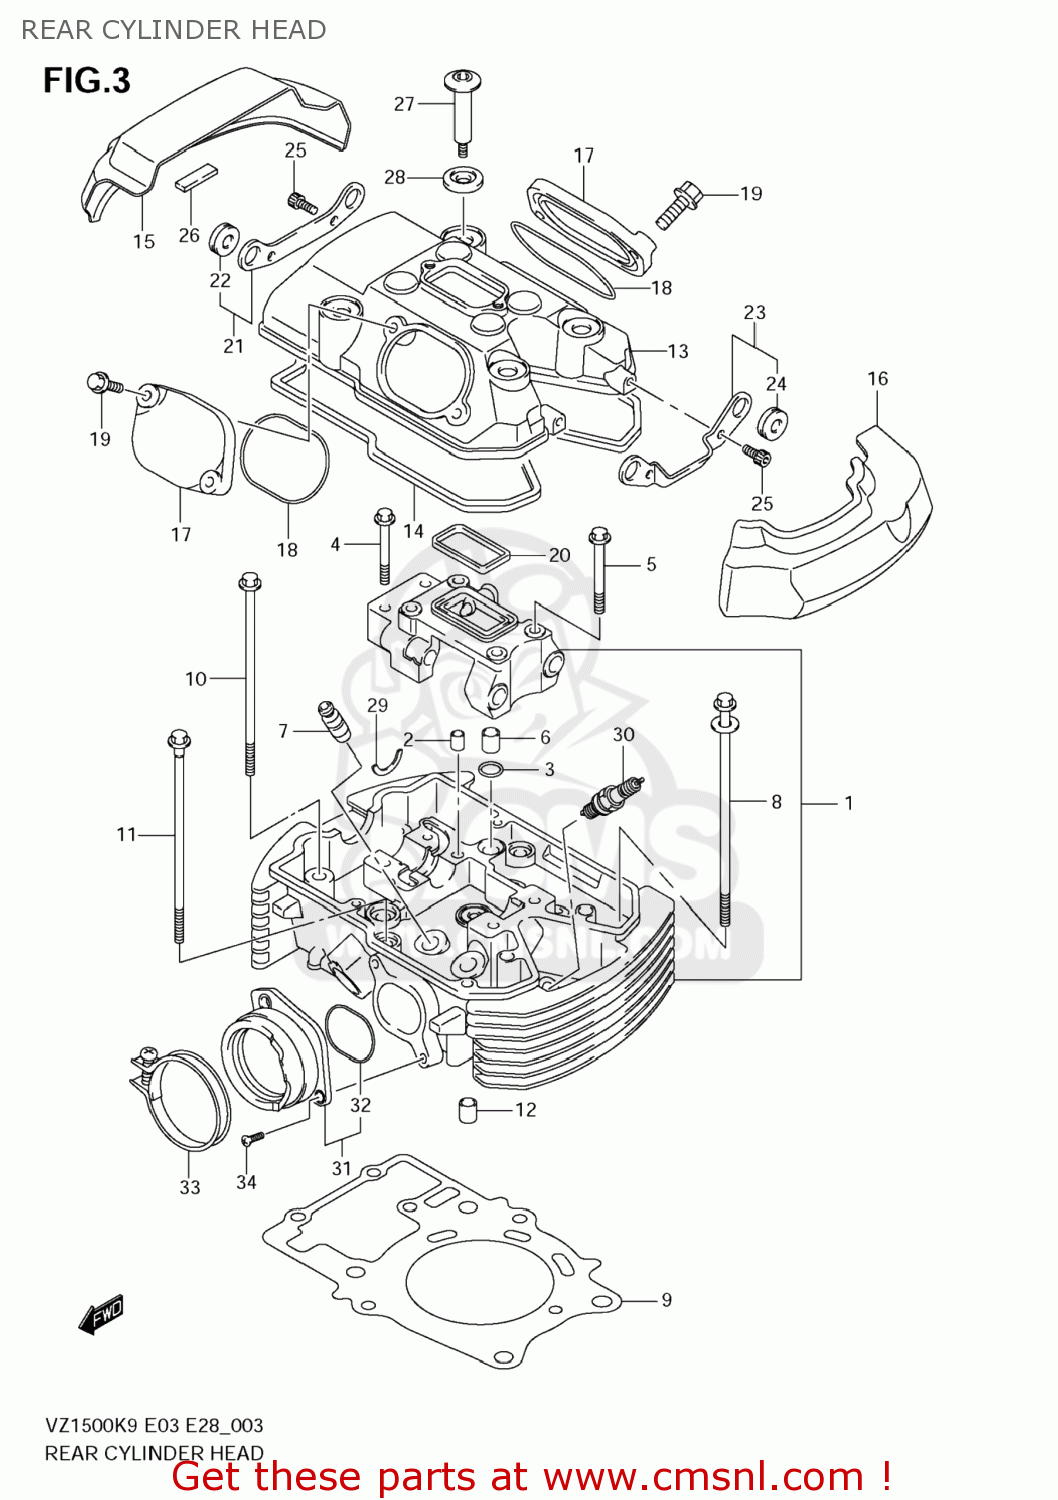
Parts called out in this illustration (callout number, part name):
1	HEAD ASSY,CYLINDER RR
2	PIN(6.2X8X11)
3	O RING(D:2.4,ID:10.8)
4	BOLT
5	BOLT
6	PIN
7	GUIDE,VALVE
8	BOLT,CYLINDER HEAD(L:190)
9	GASKET,CYLINDER HEAD RR (NAS)
10	BOLT(8X160)
11	BOLT(8X180)
12	PIN
13	COVER,CYLINDER HEAD
14	GASKET,CYL HEAD COVER NO.1 (NAS)
15	CAP,CYLINDER HEAD COVER NO.4
16	CAP,CYLINDER HEAD COVER NO.2
17	CAP,INSPECTION
18	O RING(D:2.4,ID:23)
19	BOLT
20	GASKET,CYL HEAD COVER NO.2 (NAS)
21	BRACKET,HEAD COVER CAP NO.1
22	CUSHION
23	BRACKET,HEAD COVER CAP NO.2
24	CUSHION
25	BOLT
26	CUSHION,PANEL NO.2
27	BOLT(7X57)
28	WASHER,CYL HEAD COVER
29	C RING
30	PLUG,SPARK(CR6E)
31	PIPE ASSY,INTAKE RR
32	O RING(D:2.4,ID:44.7)
33	CLAMP,INTAKE PIPE
34	BOLT(6X20.5)
